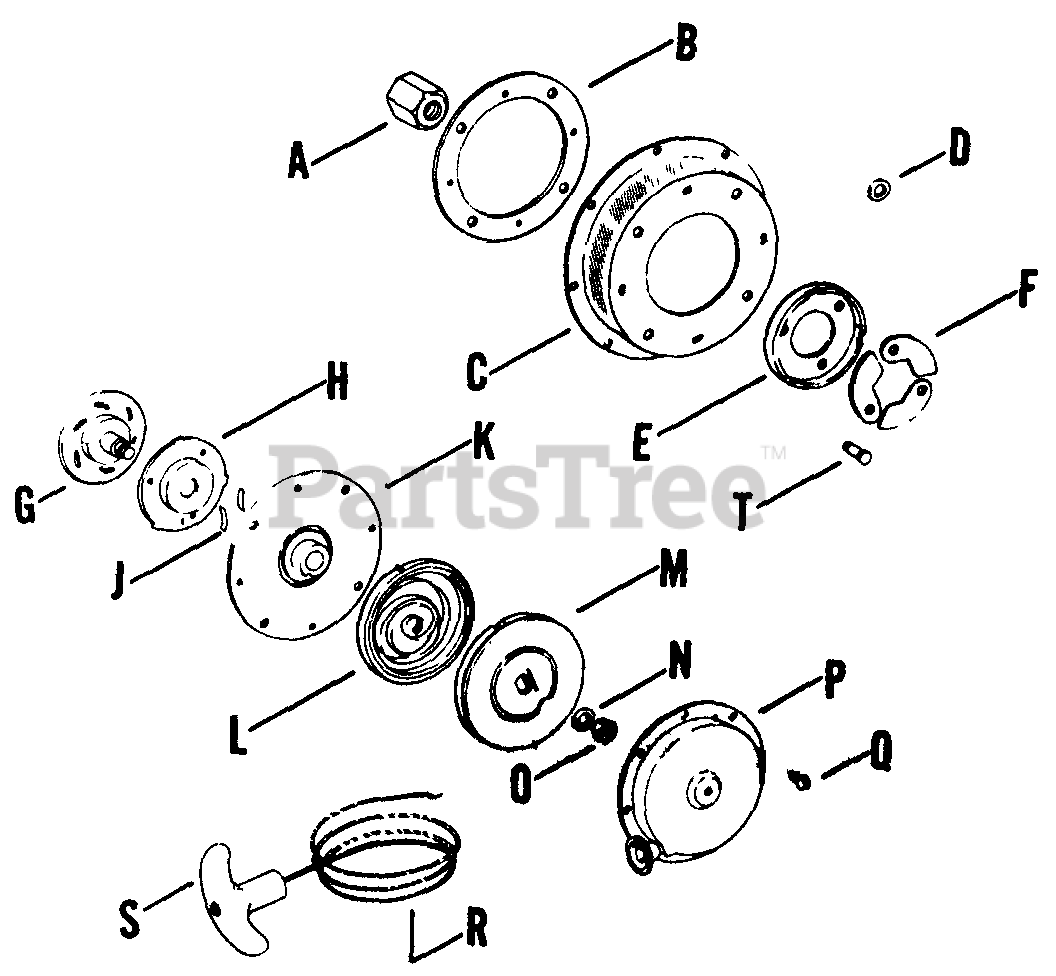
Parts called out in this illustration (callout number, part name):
B-230302	STARTER - USE 221506
B	Plate, nut
C	Housing, starter
K	Plate, mounting
L	SPRING - DISCONTINUED
N	Washer
O	Nut, self-lock
P	Housing, sheave
Q	SCREW - DISCONTINUED
R	CABLE - DISCONTINUED
S	HANDLE - DISCONTINUED
